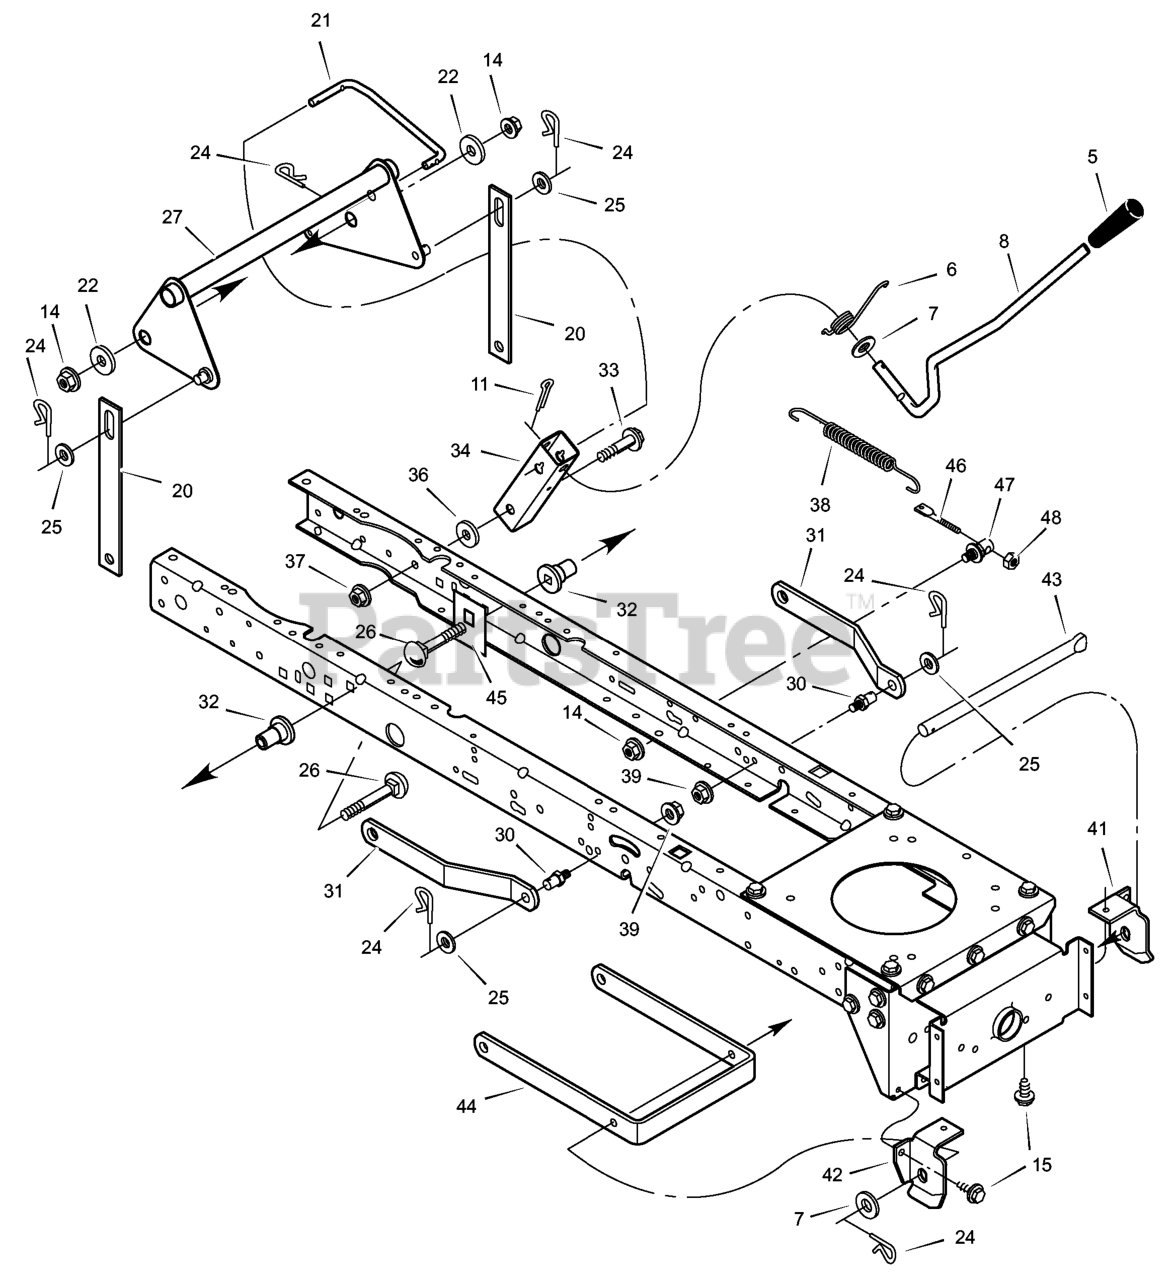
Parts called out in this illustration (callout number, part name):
5	Grip
8	Lever, Lift
11	Pin, Cotter
14	Nut, Flange
20	Link, Lift
21	Link, Lift Handle
24	Pin, Hair
26	Bolt, Carriage
27	Lever Assembly, Lift
30	Pin
31	Bracket, Rear Suspension
32	Spacer, Lifter
33	Bolt, Shoulder
34	Bracket, Pivot
37	Nut, Flange
39	Nut, Flange
41	Hanger, Left Deck
42	Hanger, Right Deck
43	Rod, Hanger
44	Bracket, Suspension
45	Plate, Stiffening
46	Stud, Spring Mount
47	Stud, Swivel
48	Nut
